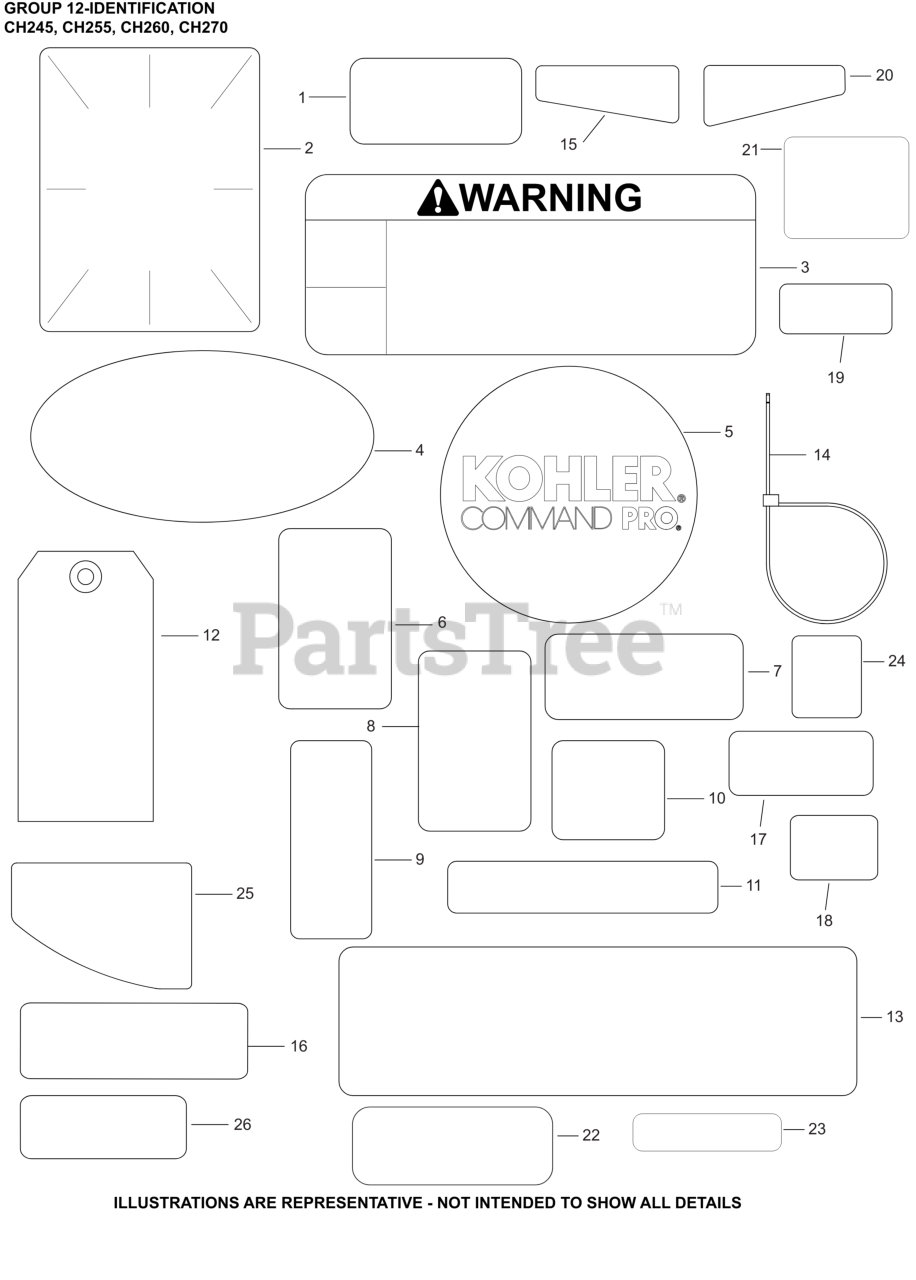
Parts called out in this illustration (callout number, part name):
1	LABEL, MAINTENANCE (CKY)
2	LABEL, CLEAR LAMINATION
3	DECAL, WARNING
4	DECAL, QUAD CLEAN SILVER
5	LABEL, RECOIL 62MM
6	DECAL, SNOW FLAKE
7	LABEL, CANADIAN COMPLIANCE
8	DECAL, SUN
9	DECAL, FUEL/CHOKE - ON/OFF
10	DECAL, BASE ARROW
11	DECAL, THROTTLE
17	DECAL, ETHANOL WARNING
